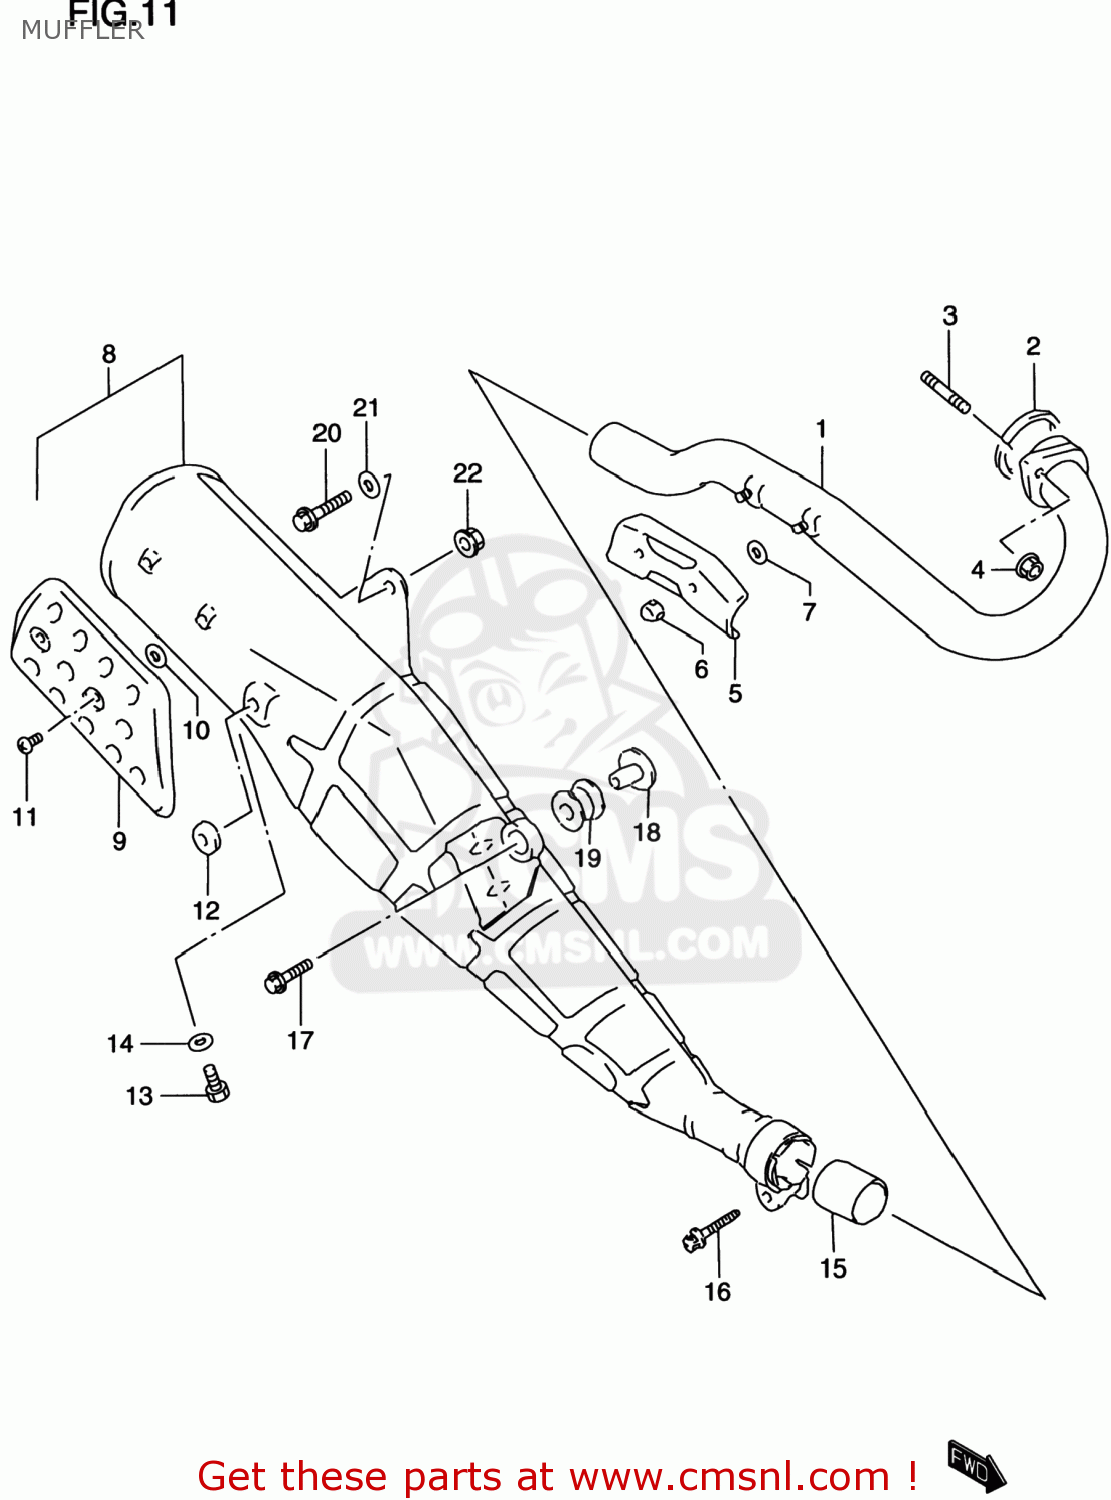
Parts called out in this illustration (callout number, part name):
1	PIPE COMP,EXHAUST
2	GASKET,EXHAUST PIPE (NAS)
3	STUD 8X25
4	NUT
5	COVER,EXHAUST PIPE
6	NUT (M6)
7	GASKET(6X16X1.4) (NAS)
8	MUFFLER ASSEMBLY
9	COVER,MUFFLER
10	GASKET(5.8X13X1.4) (NAS)
11	SCREW(6X10)
12	CUSHION
13	PLUG(12X9)
14	GASKET(12.1X16.2X3.7) (NAS)
15	GASKET,2ND MUFFLER (NAS)
16	BOLT
17	BOLT(8X35)
18	SPACER(8.6X12X17.5)
19	CUSHION
20	BOLT(8X35)
21	WASHER
22	NUT
